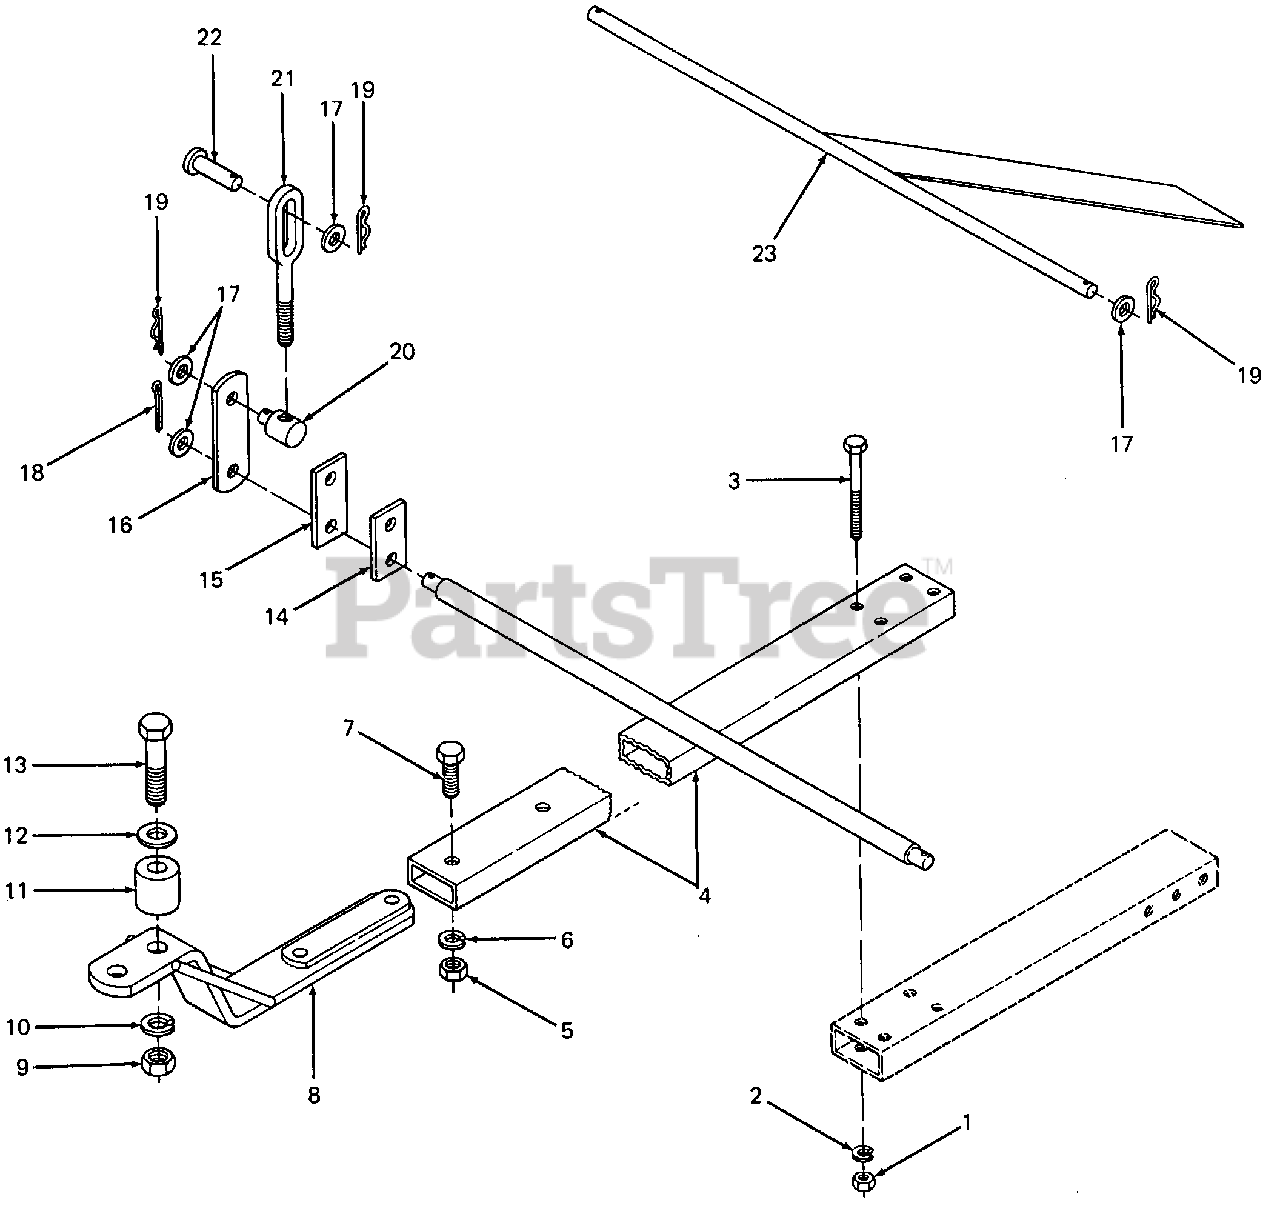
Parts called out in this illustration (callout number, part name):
1	Nut, Hex, 3/8-24
2	Washer, Lock, 3/8
3	Screw, Hex Cap, 3/8-24 X 3.75 Lg GR5
4	Bracket, Lift
5	Nut, Hex Jam, 1/2-13
6	Washer, Lock, 1/2
7	Screw, Hex Cap, 1/2-13 X 1.5 Lg GR5
8	Bracket, Hanging
9	Nut, Hex Insert Lock, 5/8-18
10	Washer, Lock, 5/8
11	Spacer, .65 X 1.5 X 1.5 Lg
12	Washer, Flat, .64 X 1.25 X.100 Thk
13	Screw, Hex Cap, 5/8-18 X 3.0 Lg GR5
14	Link, Lift
15	Link, Lift
16	Link, Lift
17	Washer, Flat, .510 X 1.0 X .060 Thk
18	Pin, Cotter, 1/8 Dia X 1.25 Lg
19	Pin, Internal Cotter
20	Ferrule, Adjustment, 1/2-20 Trd
21	Link, Adjustment
22	Pin, Lift Bracket
23	Plate, Guide
